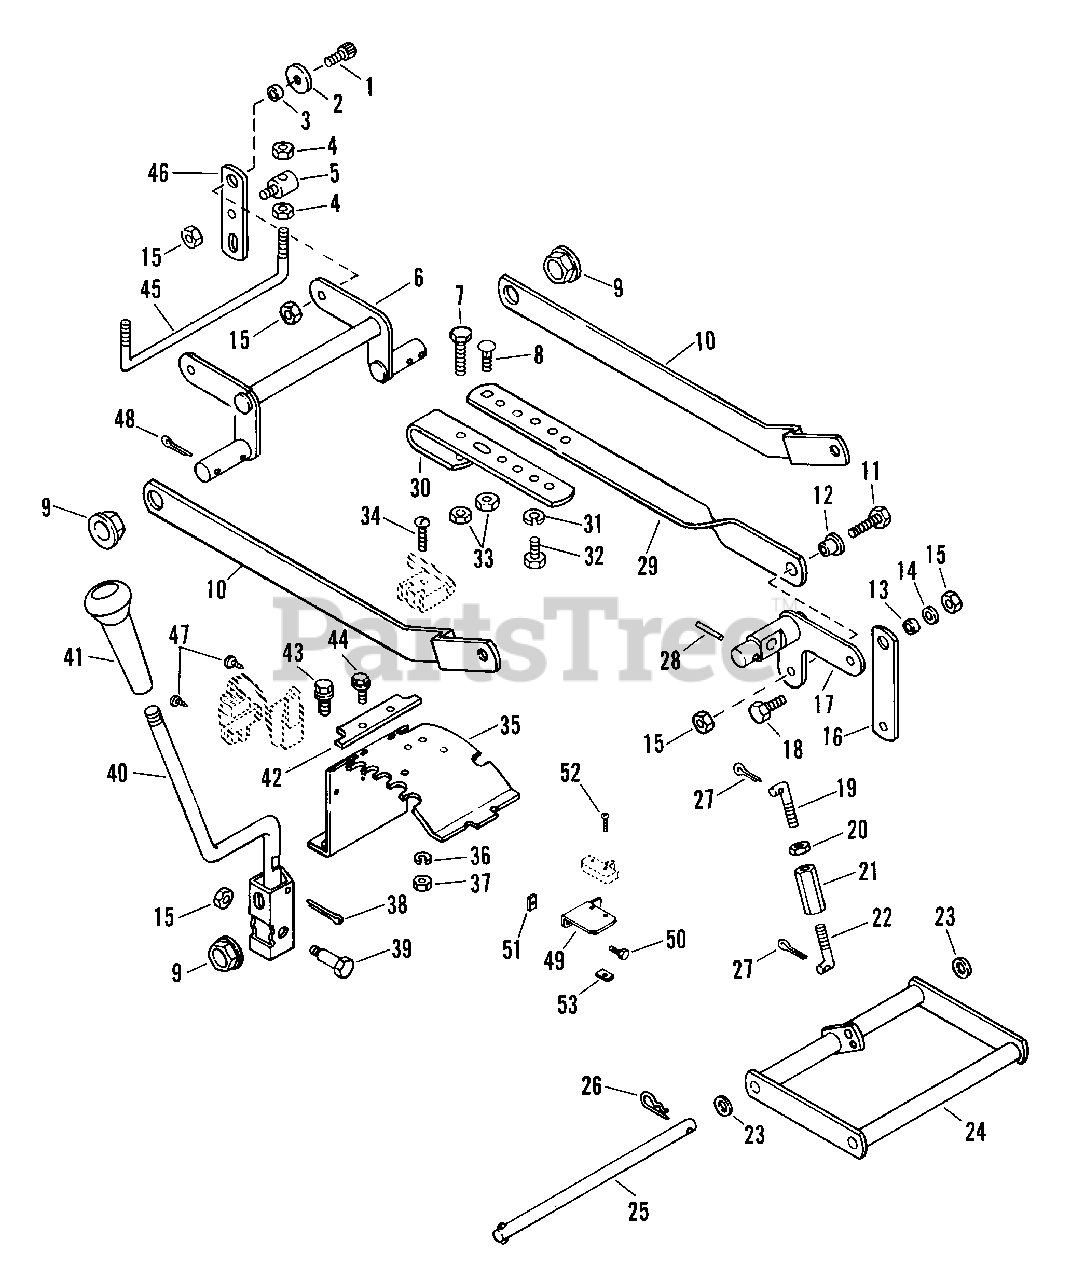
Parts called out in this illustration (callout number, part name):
1	SCR-SKH .31-18X.75 BTNHD YWZC
2	WSHR-FL-STL .344X1.125X.063PL
3	SPACER BUSHING .5 X .32 X .21
4	NUT-LK-JAM-CTR .375-16 PL
5	ROD PIVOT
6	REAR MOWER HANGER
7	BLT-HEX .38-16X1.50 PL GR2
8	BLT-RDHDSQNK .38-16X.75 SHT PL
9	FLANGE BUSHING
10	POSITIONING ARM
11	BLT-HEX .31-18X1.25 PL GR2
12	SPACER -SHLD .344X.500X.469
13	SPACER BUSHING .5 X .32 X .163
14	WSHR-FL-STL .323X.625X.062 PL
15	NUT-LK .312-18 GR A PL
17	MOWER LIFT ARM
18	BLT-HEX .31-18X.75 PL GR2
19	LINK - FRONT LIFT
20	NUT-LK .375-16
21	NUT-CUPLG RH & LH THD .37-16PL
22	LINK-FRONT LIFT
23	WSHR-FL-STL .520X.827X.062 YZ
24	FRONT LIFT ARM
25	HANGER PIN
26	PIN-HAIR INT .08X.38X1.42 YWZC
27	PIN-COTR .09X.75 PL
28	PIN-ROLL .188X1.25
29	LIFT STRAP
30	ADJUSTMENT STRAP
31	WSHR-LK .375X.115 HVY PL
32	BLT-HEX .38-16X.75 PL GR2
33	NUT-LK-CTR .375-16 GR A PL
34	SCR-MCH 10-24X1.00 SLRH PL
35	QUADRANT
36	WSHR-LK 10X.047 MED PL
37	NUT-HEX 10-24 PL
38	PIN-COTR .15X1.50
39	SHOULDER BOLT .436 X .912
40	MOWER HEIGHT LEVER
43	SCR-TAP .312-18X.50 HWH PL TR
44	SCR-TAP .250-20X.37 HWH PL TR
45	ROD - REAR LIFT
46	LINK - REAR LIFT
47	SCR-TAP 12-14X.50 CRPH PL
48	PIN-COTR .09X1.0 PL
49	MOUNTING BRCKT. CLUTCH SWITCH
50	SCR-SKH 10-24X.50
51	NUT-KEPS 10-24 PL
52	SCR-MCH 6-32X1.00 SLRH PL
53	NUT-KEPS 6-32 PL
